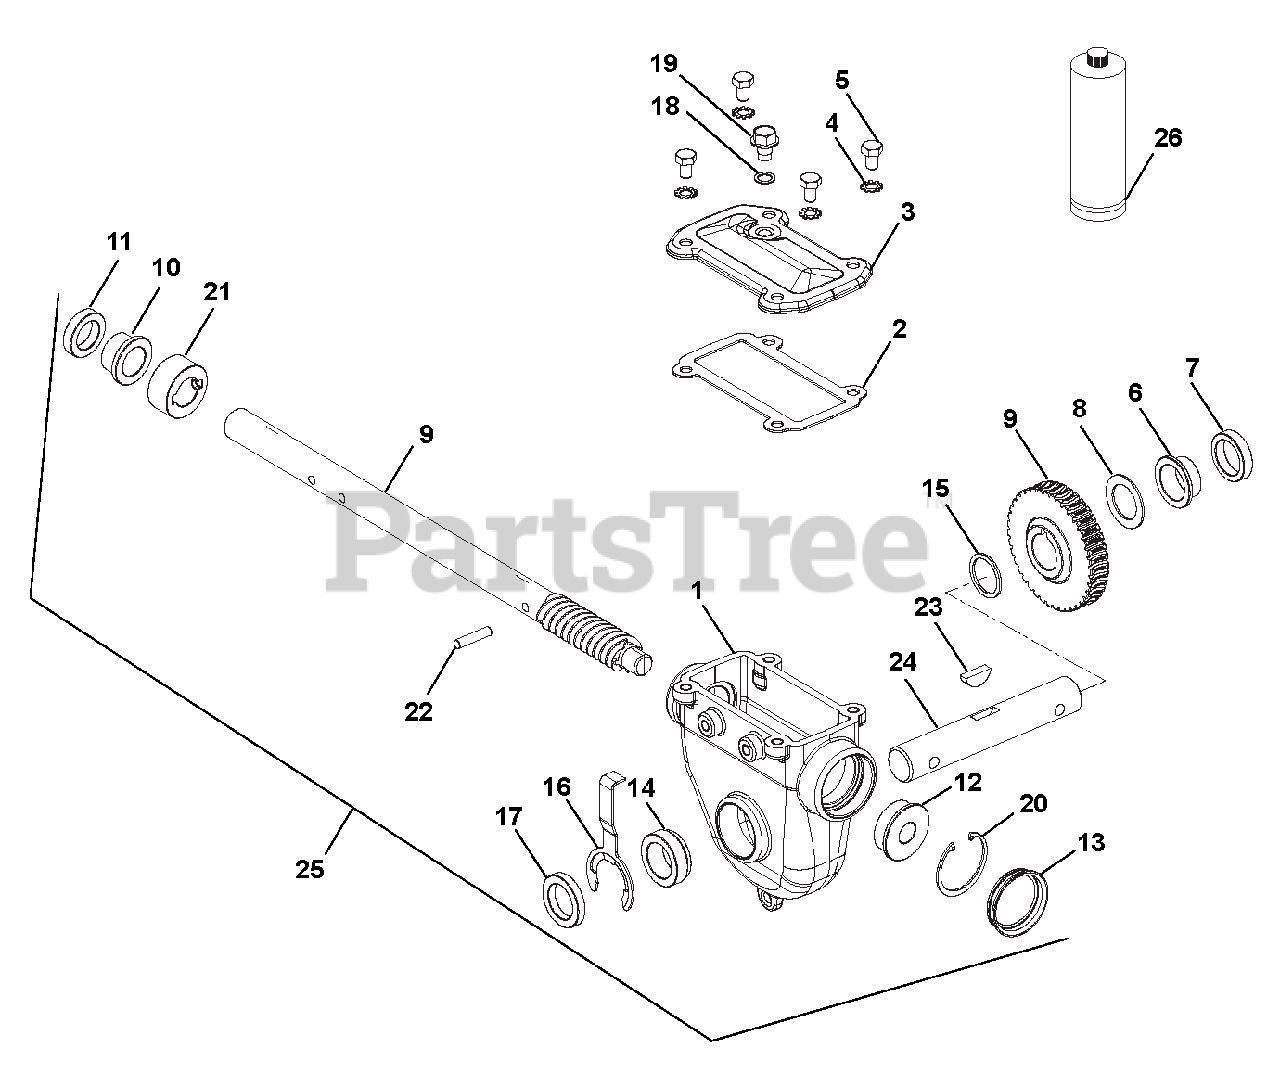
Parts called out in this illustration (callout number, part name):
1	GEARCASE, LARGE MACHINED
2	GASKET, TOP - LARGE GEARCASE
3	COVER, TOP - LARGE IRON
4	@WSHR-LK-EXT.326X.599X.031YWZC
5	@BLT-HEX .31-18X.50 GR5 YWZC
6	BSHG-FLG 1.006X1.128X.555X1.45
7	SEAL-OIL .999X1.375X.312 TB2-H
8	WSHR-FL-STL 1.010X1.505X.062YZ
9	WORM SHAFT & GEAR
10	BSHG-FLG .879X1.128X.75X1.45
11	SEAL-OIL .873X1.375X.312 TB2-H
12	BSHG-FLG .628X1.503X.58X1.725
13	COVER, GEAR CASE 1.75"
14	BSHG-FLG LARGE, RIGHT
15	WSHR-FL-STL 1.010X1.250X.068YZ
16	BUSHING RETAINER, LARGE
17	SEAL-OIL .999X1.500X.250 TB2-H
18	WSHR-BND-SEAL .38X.75X.11 GALV
19	@SCR-ROLOK .38-16X.50 HWH YWZC
20	RG-RTNG-INT 1.750X.062
21	THRUST COLLAR, .875"ID SLIPFIT
22	PIN-STR .250X1.12 6150
23	KEY-WDRF .25X.875 HRD #A
24	RAKE SHAFT, SHORT-COMMON
25	GEAR CASE ASSY - DLX IRON
26	ARIENS L3 LUBE, 8 OZ BOTTLE
